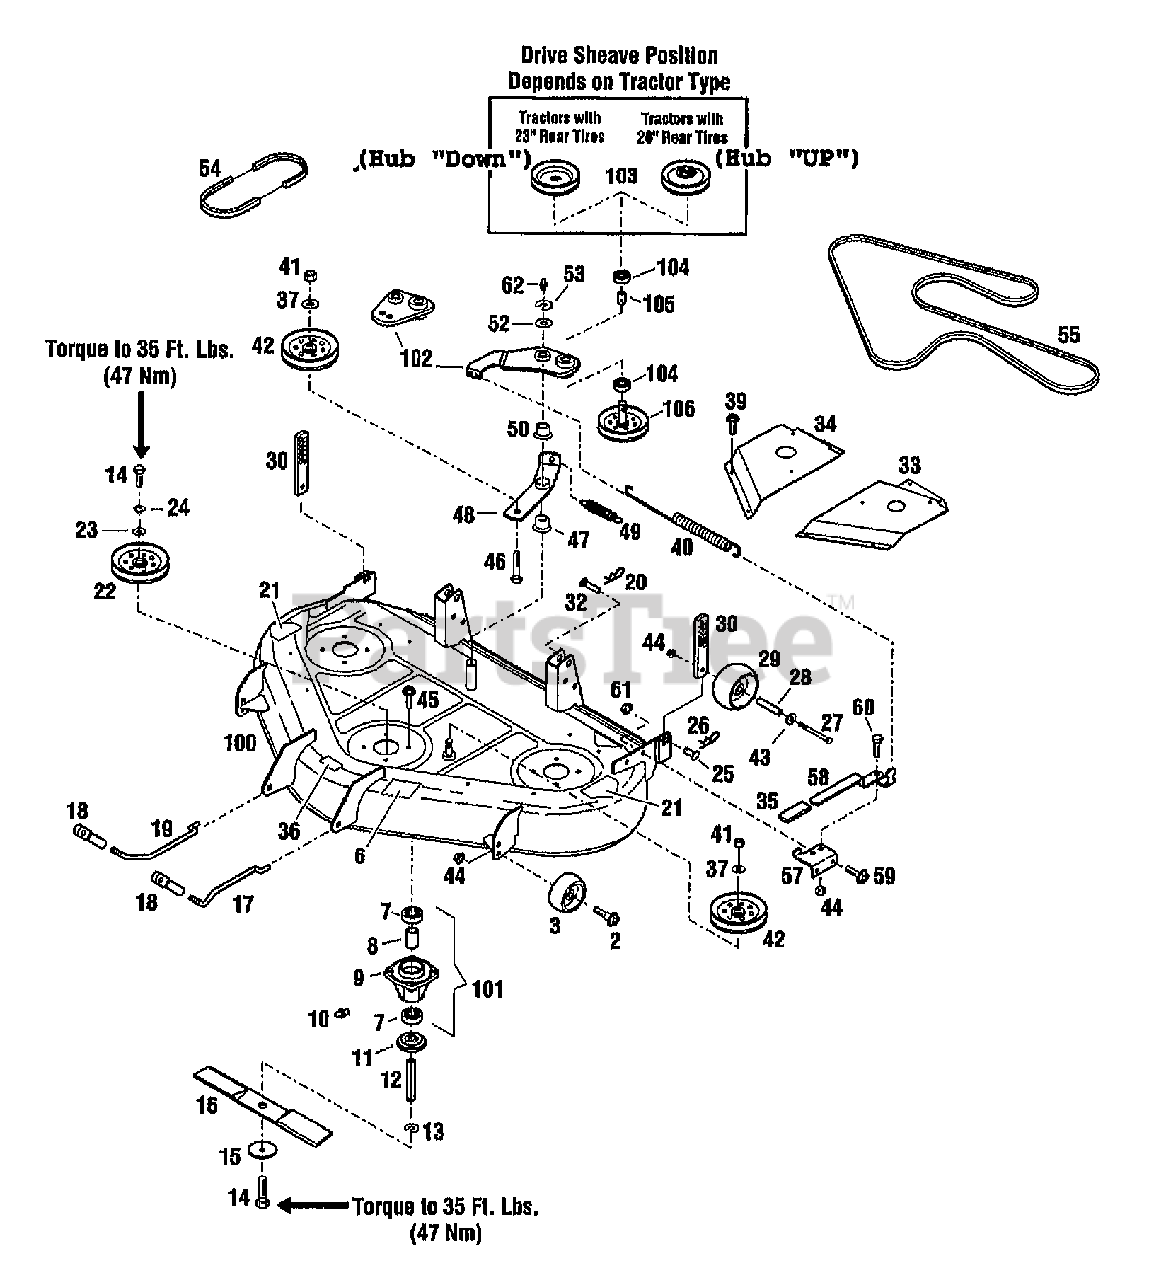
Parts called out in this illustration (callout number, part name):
2	SCR-SHLDR 3/8-16
3	WHEEL-GAGE
6	DECAL-BELT DRIVE
7	BEARING-BALL
9	HOUSING-SPINDLE
10	FITTING-GREASE 1/4-28X2.00
11	SPACER-BLADE
12	SHAFT-SPINDLE
13	RING-RETAINING EXT .694 ID
14	SCR-HH 1/2-14X1.00
15	WASHER-BELLEVILLE
16	BLADE-CUTTER
17	ROD-LIFT FRONT LH
19	ROD-LIFT FRONT RH
20	PIN-HITCH .125X2.56 ZP
21	DECAL-OPEI CAUTION
22	ASSM-SHEAVE 5"
23	WASHER-1.25X.5X.083 ZP
24	WASHER-LK .438 ZP
25	PIN-CLEVIS .375 X .937 ZP
26	CLIP-HAIRPIN .07 DIA
27	SCR-HH 3/8-16X3.5 G5 ZP
28	SPACER-GAGE WHEEL
29	WHEEL-GAGE
30	LEVER-GAGE WHEEL ADJUST
32	PIN-CLEVIS .625X2.25
33	COVER-BELT LH
34	COVER-BELT RH
36	DECAL-LIFT ROD
37	WASHER-FLAT .88X.5X.06 ZP
39	SCR 1/4-20X.5 FL SELF TAP
40	SPRING-BELT DRIVE
40	SPRING-EXTENSION 20.75
41	NUT-TOP LOCK 1/2-13 ZP
42	PULLEY-IDLER
43	WASHER-.986X.437X.083 ZP
44	NUT-LOCK 3/8-16
45	SCR-HFLK 5/16-18X.75
46	BOLT-CARR 1/2-13X1-3/4
47	BUSHING-FLANGE
48	ARM-IDLER
49	SPRING-EXTENSION
50	BEARING-FLANGE
52	SHIM-WASHER
53	RING-RET. EXT .875 ID
54	BELT-V
57	BRKT, SPRING ARM
57	BRKT-LONG SPRING ARM
58	ARM-SPRING ENGAGE
58	ARM-SPRING ENGAGEMENT
59	SCR-HFLK 5/16-18X.75 ZP
60	SCR-HH 3/8-16X1.0 G5 ZP
61	NUT-HFLK 5/16-18 ZP
62	FITTING-GREASE 90 DEGREE
100	DECK-MOWER W/DECALS
101	ASSM-MOWER SPINDLE
102	ARM-MOUNTING
102	WELDMENT ASSM-MTG ARM
103	PULLEY-DRIVE
104	BEARING-BALL
105	SPACER-1.04X.875X1.07
106	PULLEY W/SHAFT
